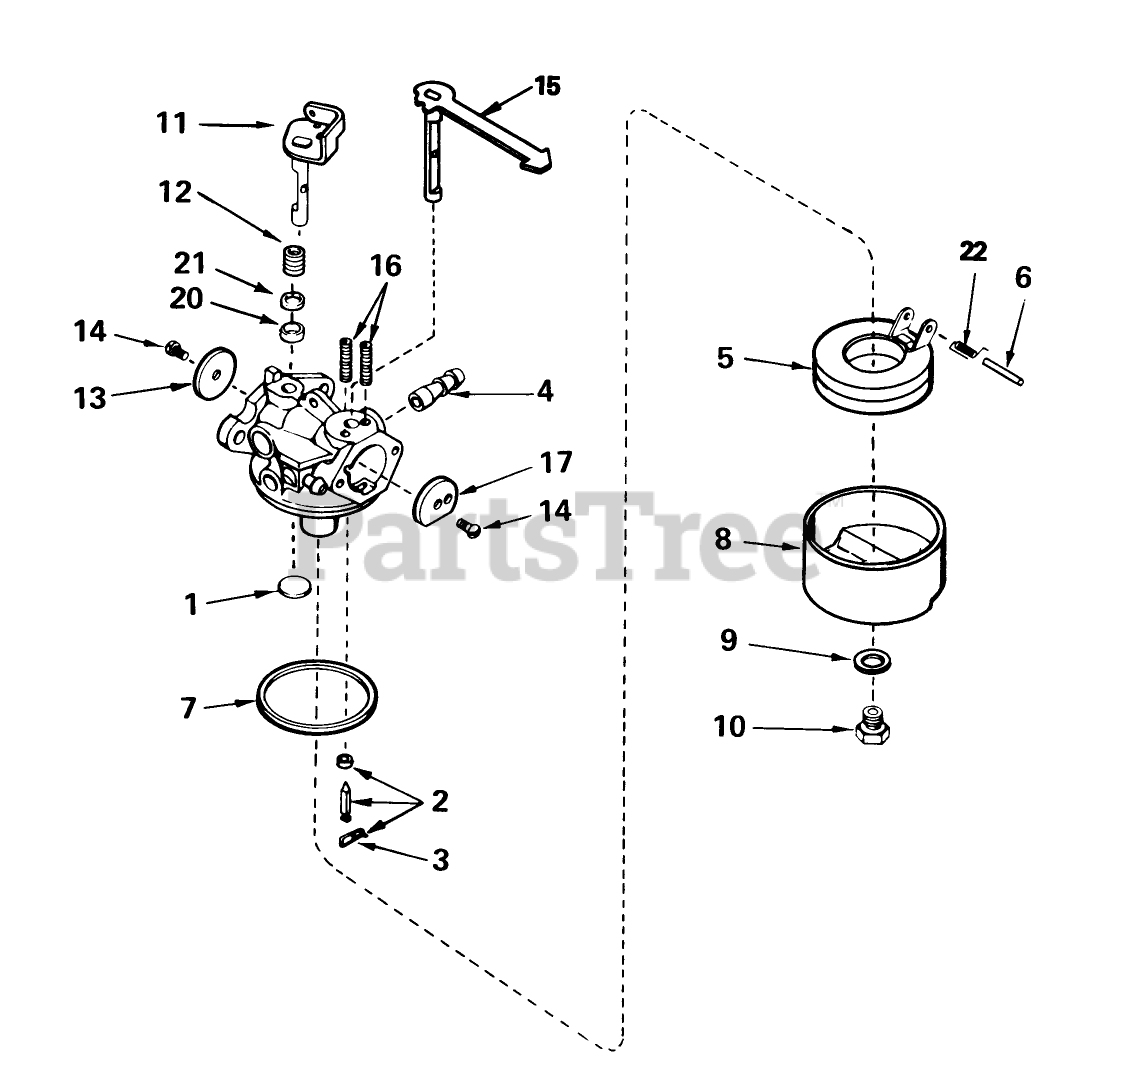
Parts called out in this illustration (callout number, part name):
1	Plug-Welch, Atmospheric Vent
2	Inlet Needle, Seat Clip Assy. (Incl. No. 13)
3	Clip-Spring
4	Fitting-Fuel
5	Float
6	Shaft-Float
7	O Ring-Bowl, Float
8	Bowl Float
9	Gasket-Bowl
10	Nut-Float Bowl
11	Shaft/Lever-Throttle
12	Spring-Trottle, Return
13	Shutter-Throttle
14	Screw-Shutter
15	Choke Shaft Lever Assy.
16	Spring-Positioning, Choke
17	Shutter-choke
20	Seal-Dust
21	Washer-Seal, Dust
22	Spring-Float, Dampening
